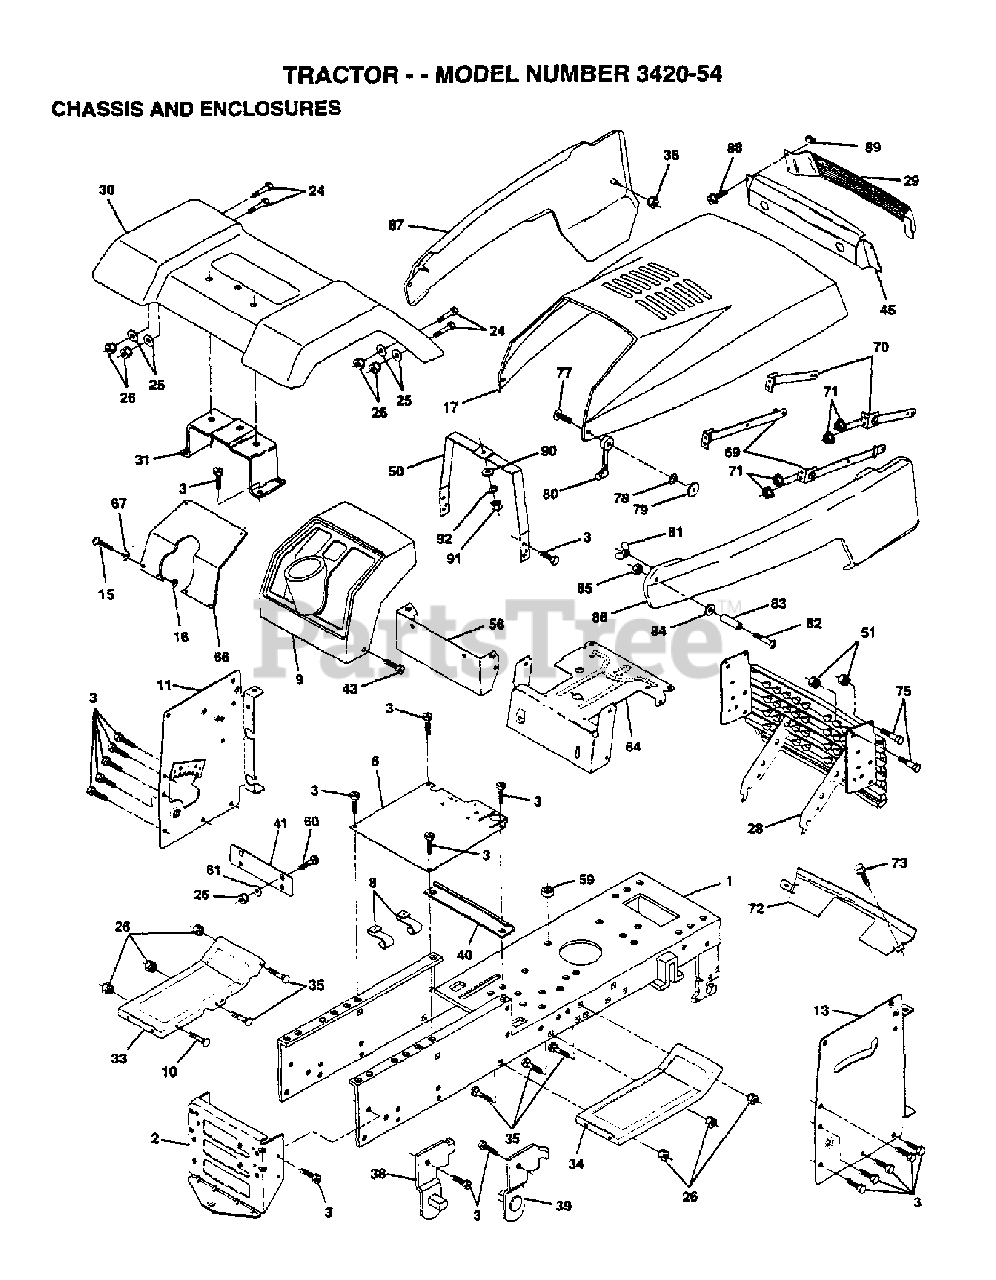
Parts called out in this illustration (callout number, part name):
2	Poulan TBD
8	CLIP,INSULATOR
17	Poulan TBD
25	WASHER
26	NUT
30	Poulan TBD
31	BRACKET.SUPPORT.FENDER
33	Poulan TBD
34	Poulan TBD
36	PAL NUT LT
38	BRACKET LH PIVOT
39	BRACKET RH PIVOT
41	Plate
50	DASH SUPT YP
51	NUT.CROWNLOCK.1/4
66	Poulan TBD
67	WASHER
71	NUT.HEX.KEPS.1/4-20
72	Poulan TBD
73	SCREW CRT
75	Bolt
77	SCREW
78	LOCKWASHER
79	NUT.WELD
80	LATCH.HOOD.
81	WING NUT
82	SCREW
83	SPACER LT
84	WASHER
85	NUT **
86	Poulan TBD
87	Poulan TBD
90	WASHER PM
91	NUT
92	LOCKWASHER
129	DASH EXT PNT
